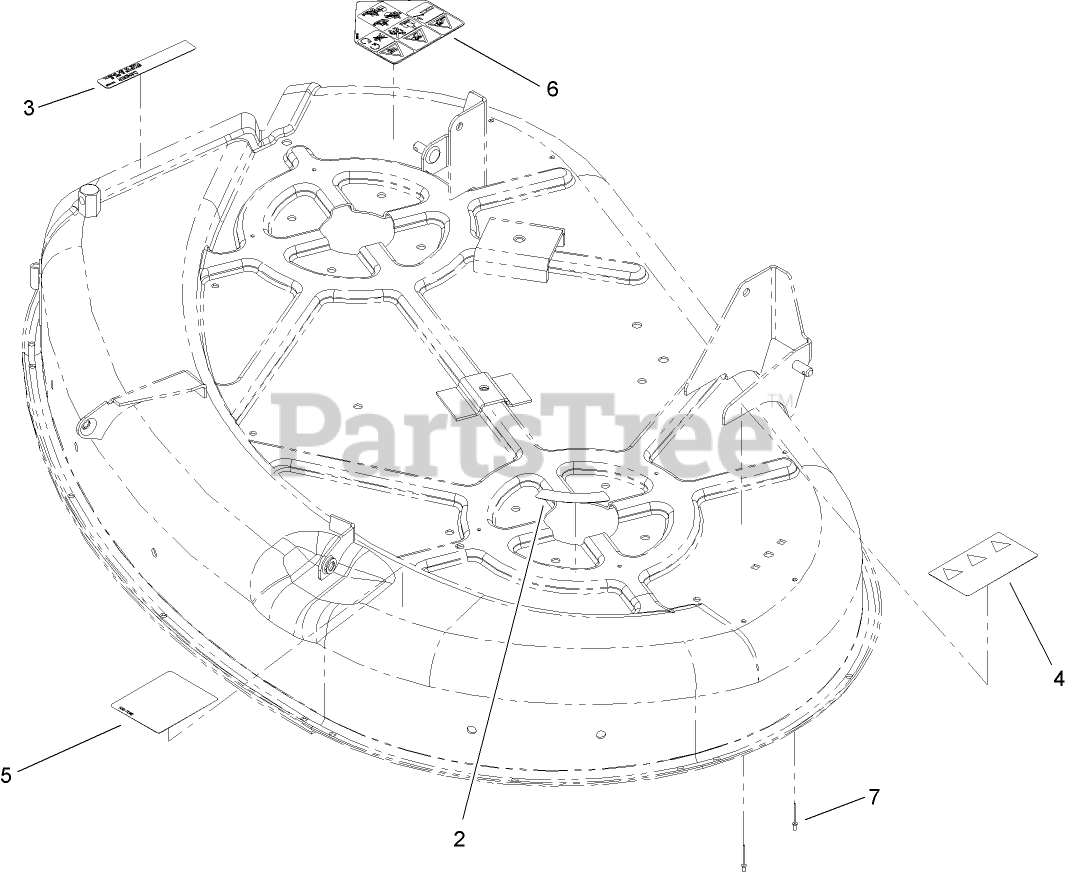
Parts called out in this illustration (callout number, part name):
2	DECAL-DANGER, SHIELD
3	DECAL-DANGER
4	DECAL-DANGER
5	DECAL-ROUTING, BELT
6	DECAL-DANGER, SHIELD
7	RIVET-BLIND
